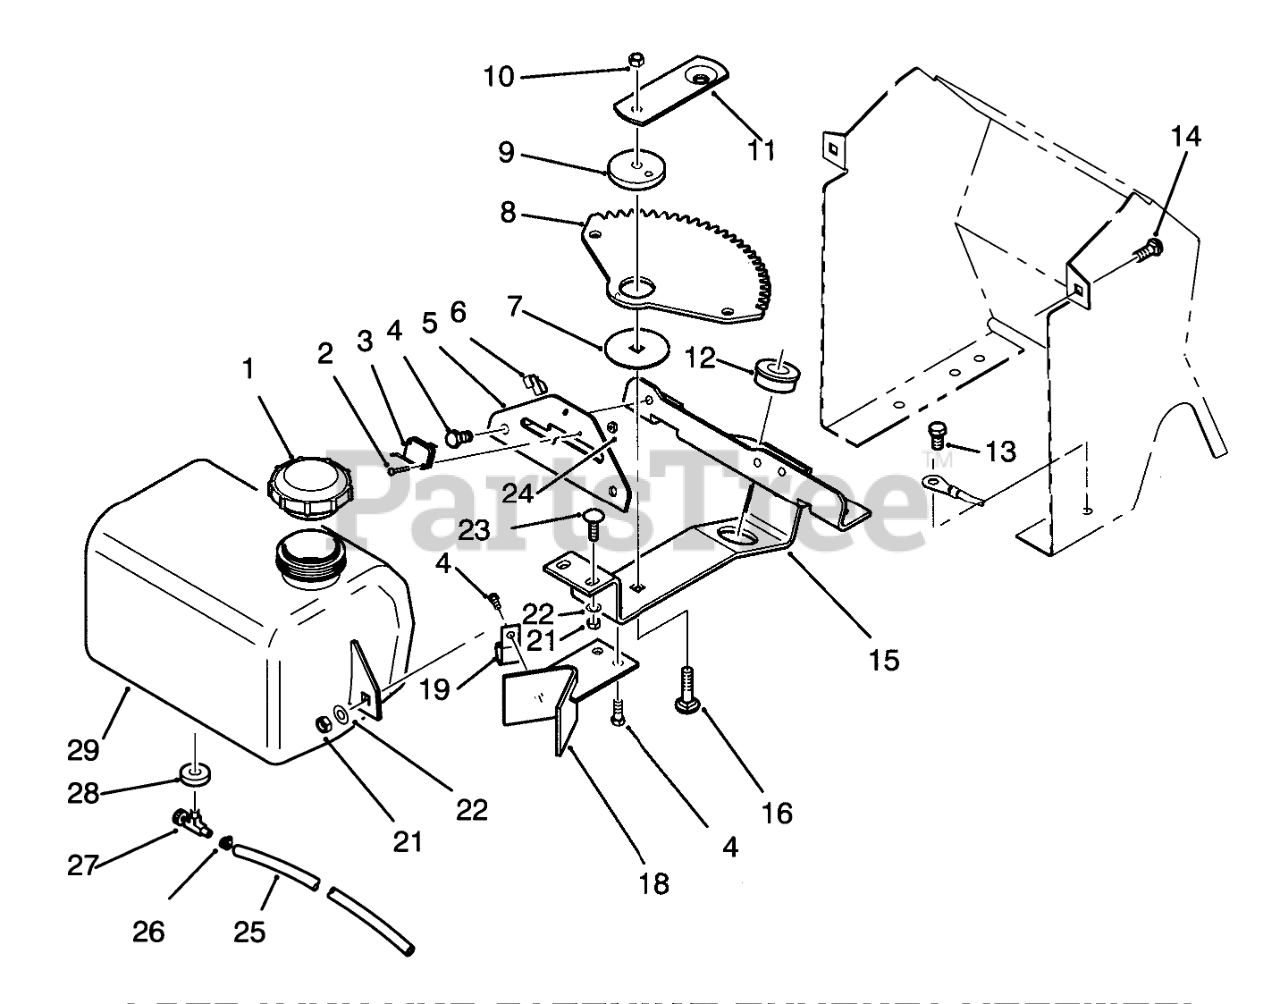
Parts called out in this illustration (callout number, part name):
1	CAP GAS
2	Screw
3	SWITCH - CLUTCH
4	Screw
5	PLATE SHIFT R
6	CLIP-CABLE
7	WASHER-BEARING
8	GEAR-SECTOR
9	BUSHING
11	Plate
12	BEARING-WHEEL
13	SCREW
14	SCREW-CARR
15	STEERING BRKT - W/A R
16	BOLT-CARR
18	Stop
19	CLIP
21	NUT-LOCK, NI
22	WASHER-PLAIN
23	Bolt-Carriage
24	NUT HEX 4-40 ELAST
25	HOSE - FUEL LINE
26	CLAMP-HOSE
27	VALVE-FUEL
28	BUSHING
29	Fuel Tank
